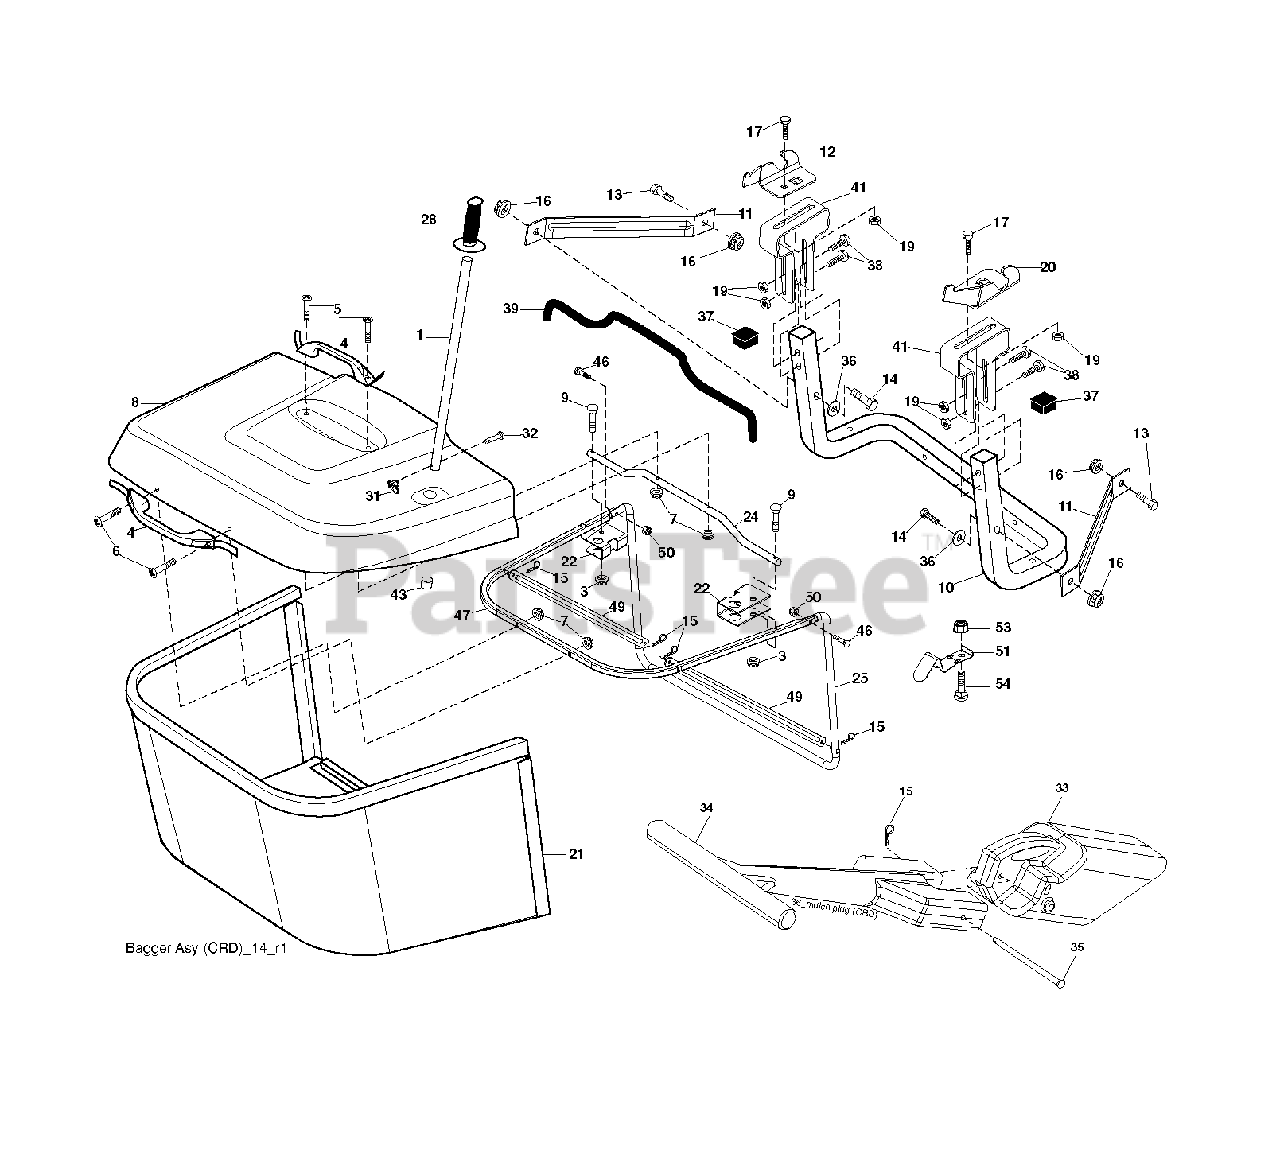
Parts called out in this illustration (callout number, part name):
1	TUBE HANDLE
3	NUT T
5	SCREW.PAN.HEAD
11	BRACKET
14	BOLT-HEX EAK
15	RETAINER-SPRNG RB
16	NUT LOCK FLG 3/8-16 UNC
17	BOLT
19	NUT LOCK HEX FLANGE 5/16-18
20	BRKT.PIVOT.RH.CRD
21	BAGGER.ASM.CRD.2007
22	BRACKET
24	TUBE
28	GRIP.HANDLE.BLACK
31	RETAINER CLIP
32	RIVET,DRILLED
33	MULCH PLUG, CTH150
35	PIN
38	BOLT.5/16-18X2.5
39	SEAL.BAGGER.CRD
41	BRKT, BAGGER
43	PLUG, TUBING END
46	BOLT.CARRIAGE.5/16-18
50	NUT.71038.31-18.HEX.NYLOCK
53	NUT
54	BOLT
